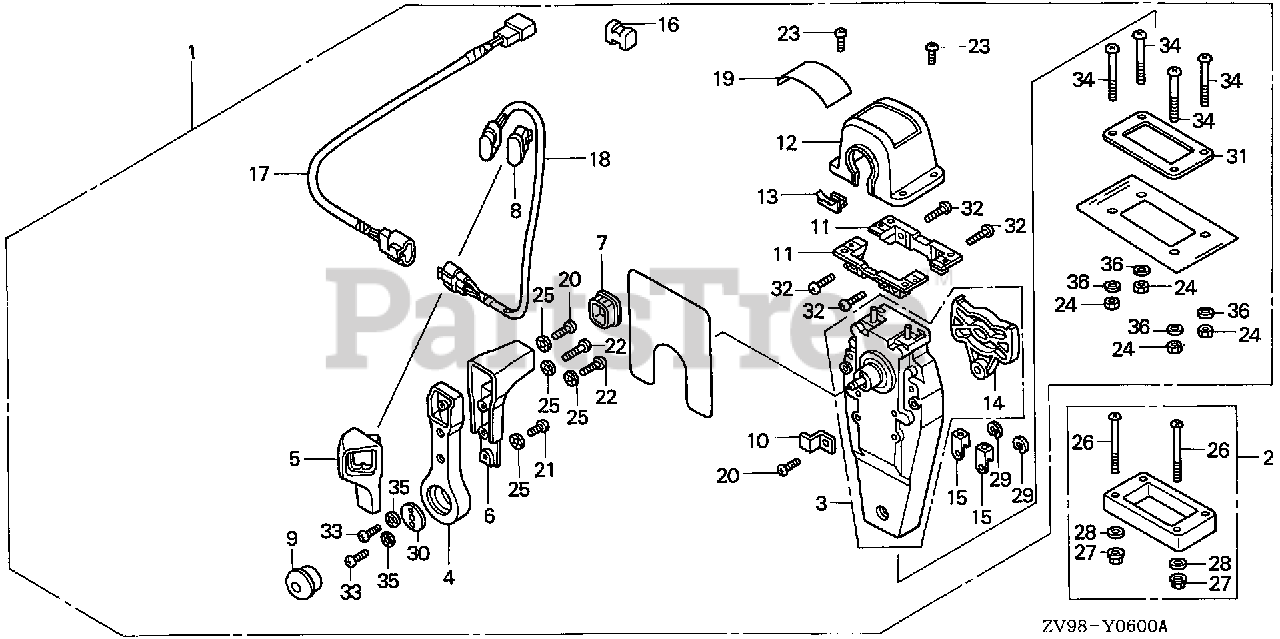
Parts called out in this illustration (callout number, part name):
1	BOX KIT, REMOTE CONTROL (TOP MOUNT SINGLE)(R)
2	SPACER KIT, REMOTE CONTROL BOX (TOP MOUNT SINGLE)
3	HOUSING ASSY., L. (INNER) (TOP MOUNT)
4	HANDLE, REMOTE CONTROL
5	COVER, L. GRIP
6	GRIP, REMOTE CONTROL HANDLE
7	CAP, GRIP
8	CAP, SWITCH
9	BUTTON, THROTTLE
10	PLATE, CABLE CLAMP
11	BRACKET, REMOTE CONTROL HOUSING
12	HOUSING, REMOTE CONTROL BOX
13	HOUSING, LEAD
14	PLATE, DWELL
15	TERMINAL, CABLE
16	SPACER, CABLE CLAMP
17	SUB-HARNESS ASSY., POWER TRIM-TILT (A)
18	SWITCH ASSY., POWER TRIM-TILT (A)
19	MARK, REMOTE CONTROL (SINGLE)
20	SCREW, PAN (5X16)
21	SCREW, PAN (5X10)
22	SCREW, PAN (5X20)
23	SCREW, PAN (4X10)
24	NUT, HEX. (5MM)
25	WASHER, LOCK (5MM)
26	SCREW, PAN (5X65)
27	NUT, FLANGE (5MM)
28	WASHER, PLAIN (5MM)
29	E-RING (6MM)
30	PLATE, HANDLE
31	GASKET, SINGLE
32	SCREW, PAN (5X18)
33	SCREW, PAN (6X18)
34	SCREW, PAN (5X40)
35	WASHER, LOCK (6MM)
36	WASHER, PLAIN (5MM)
